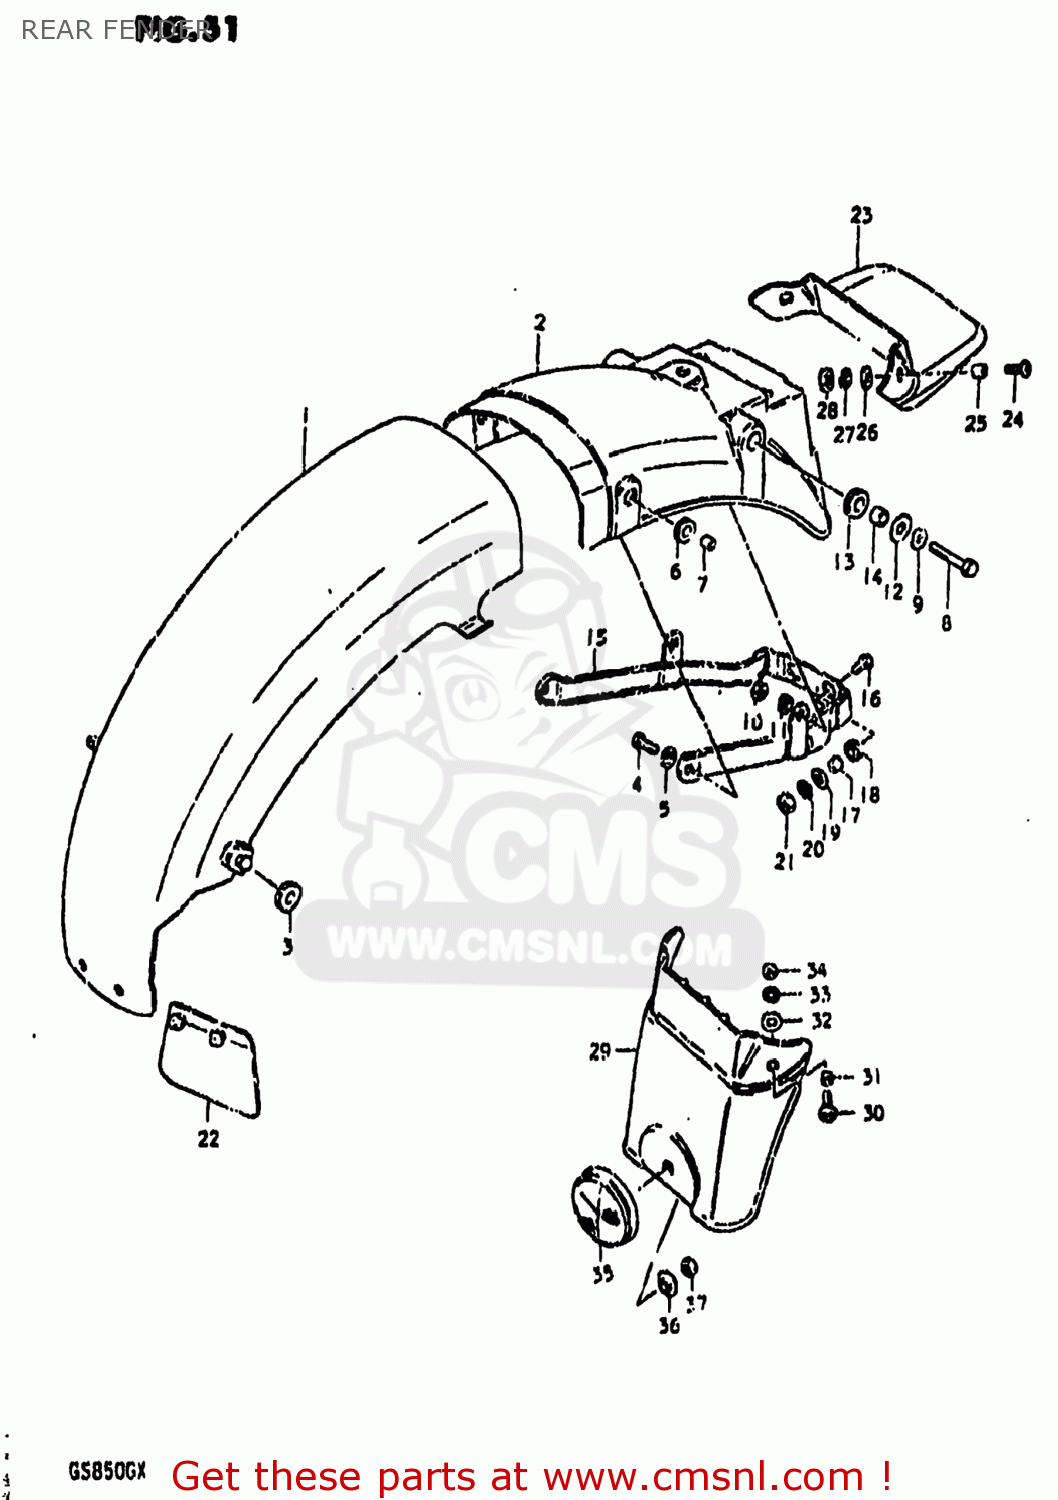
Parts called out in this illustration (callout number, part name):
1	FENDER,REAR
2	BODY,RR FENDER RR
3	CUSHION
4	BOLT
5	LOCK WASHER
6	CUSHION
7	SPACER(6.1X9X7.5)
8	BOLT
9	WASHER
10	NUT
11	LOCK WASHER
12	WASHER(8.5X26X1.2)
13	CUSHION
14	SPACER (8.2X12X7.5)
15	REINFORCEMENT,REAR FENDER
16	SCREW
17	SPACER (6.1X9X9)
18	CUSHION
19	WASHER(6,5X22X1.6)
20	LOCK WASHER
21	NUT
22	GUIDE,RR FENDER MUD
23	EXTENSION,REAR FENDER
24	SCREW (6X15)
25	SPACER(6.2X8.3X5.7)
26	WASHER(6.5X18X1)
27	LOCK WASHER
28	NUT
29	EXTENSION,REAR FENDER
30	SCREW (6X15)
31	SPACER(6.2X8.3X5.7)
32	WASHER(6.5X18X1)
33	LOCK WASHER
34	NUT
35	REFLEX REFLECTOR,RR
36	SPACER
37	NUT
